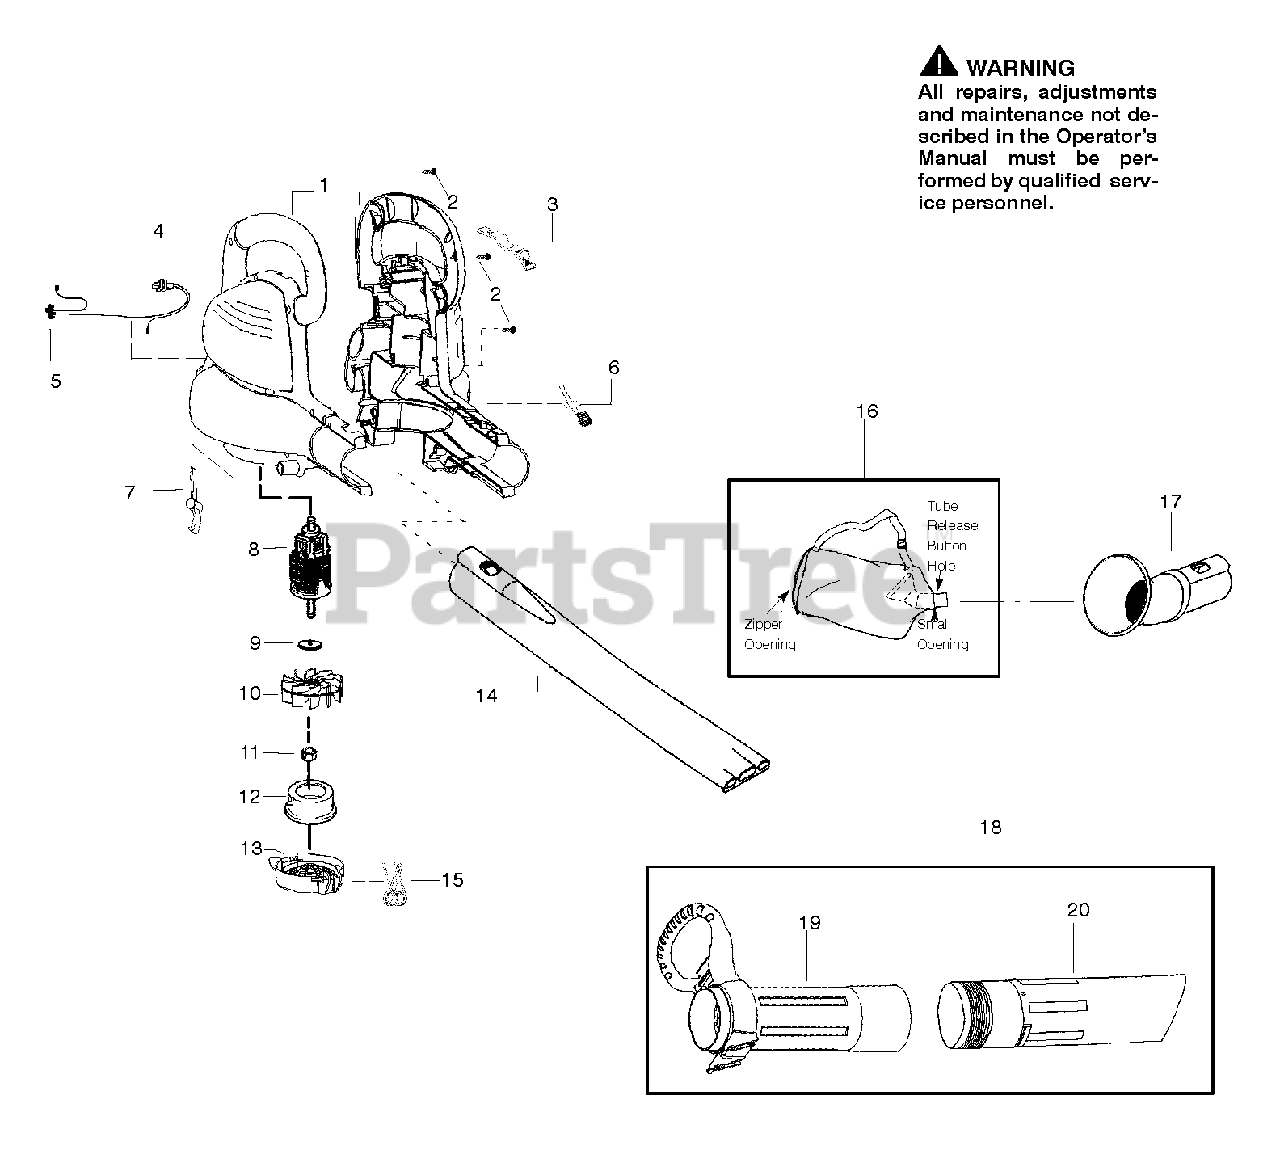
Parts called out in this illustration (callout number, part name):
1	Housing Set
3	Cover - Switch
4	Assy. Wiring Harness
6	Button - Tube Latch
7	Button - Door Latch
8	Assy. Motor
10	Impeller
11	Nut - Impeller
12	Restrictor - Inlet
13	Door - Vacuum Inlet
14	Tube - Blower
15	Spring - Door
16	Assy. - Vac Bag
17	Tube - Elbow
18	Kit-Upper/Lower Tube w/handle
19	Tube - Upper Vac w/handle
20	Tube - Lower Vac
